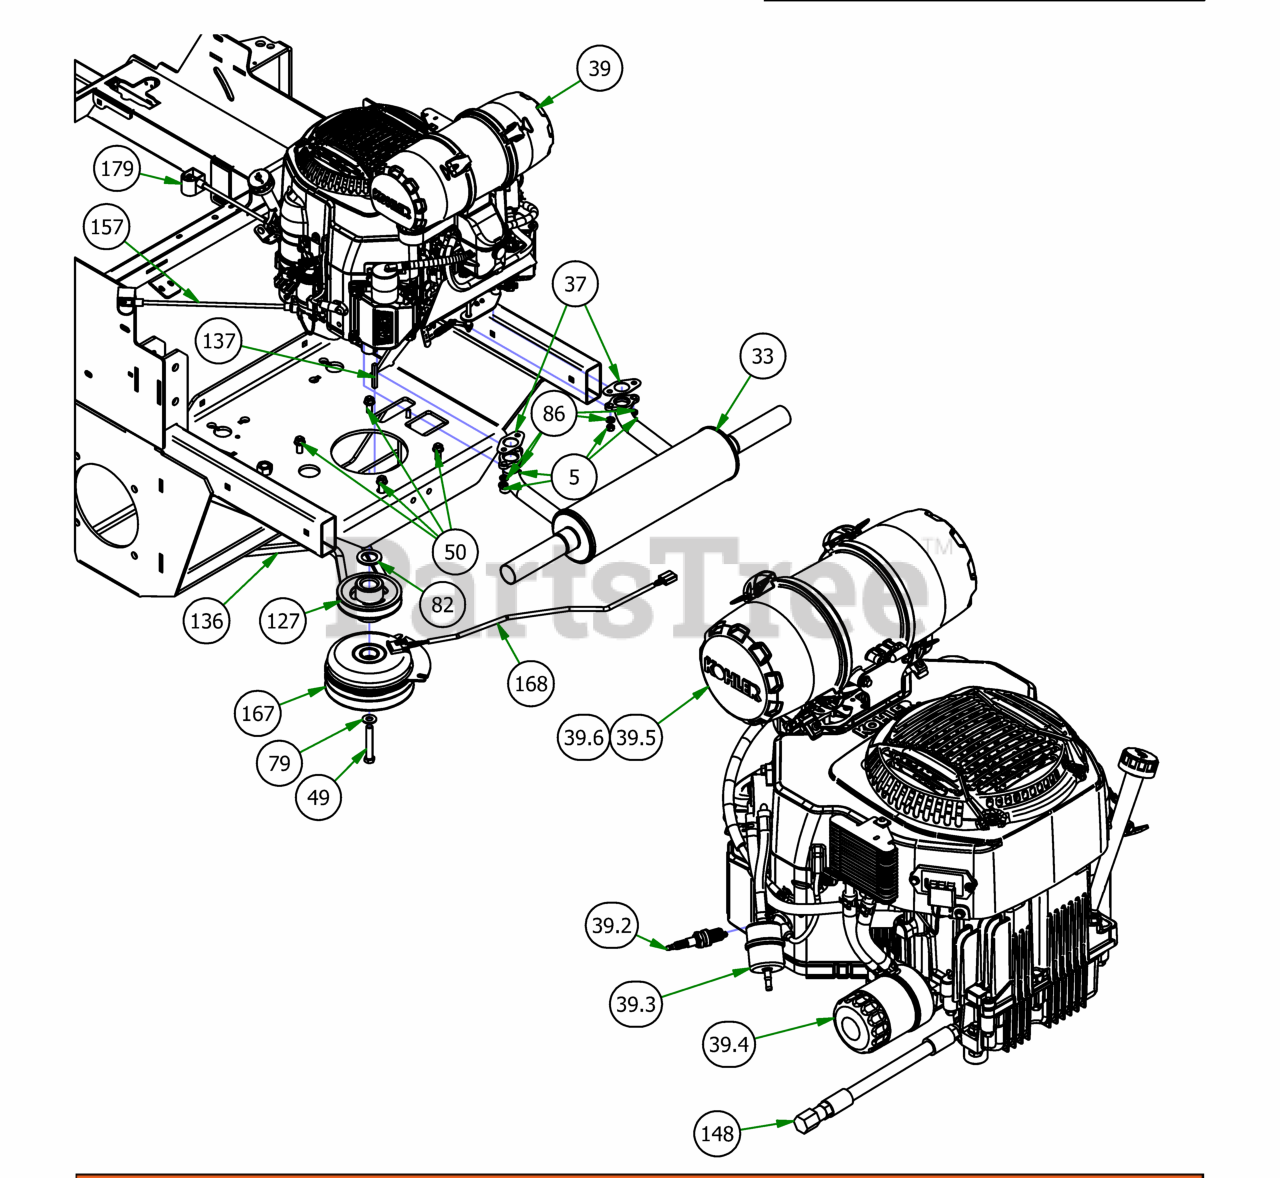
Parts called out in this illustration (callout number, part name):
5	M8-1.25 Zinc Nut
10	3/8-16 HEX SERRATED FLANGE NUT HARD/ZINC
33	2019 Rebel Kohler CV752 Muffler
37	Exhaust Gasket
39	Kohler Command Engine
39.2	Spark Plug
39.3	25/26 HP Kohler Fuel Filter
39.4	Oil Filter
39.5	Canister Air Filter- Outer
39.6	Canister Air Filter- Inner
49	7/16-20 x 2 3/4 Hex C/S GR 8 Yellow Zinc
50	3/8 x 1 1/8 bolt
72	3/8-16 X 1-1/2 HEX CAP SCREW (GR.5) ZINC
79	3/8 FLAT WASHER USS (1" OD) ZINC
82	1 1/8" Flat Spacer
86	5/16" Lock Washer
127	4 3/4 Motor Pulley
136	2019 Rebel Pump Belt
137	1/4 x 2 Square key Stock
148	Oil drain Hose for Yamaha
157	14" Red Battery Cable-Base Outlaw
167	Clutch Assembly
168	Clutch Pigtail
169	2019 Rebel Frame - Powdercoated
179	Starter Cable
